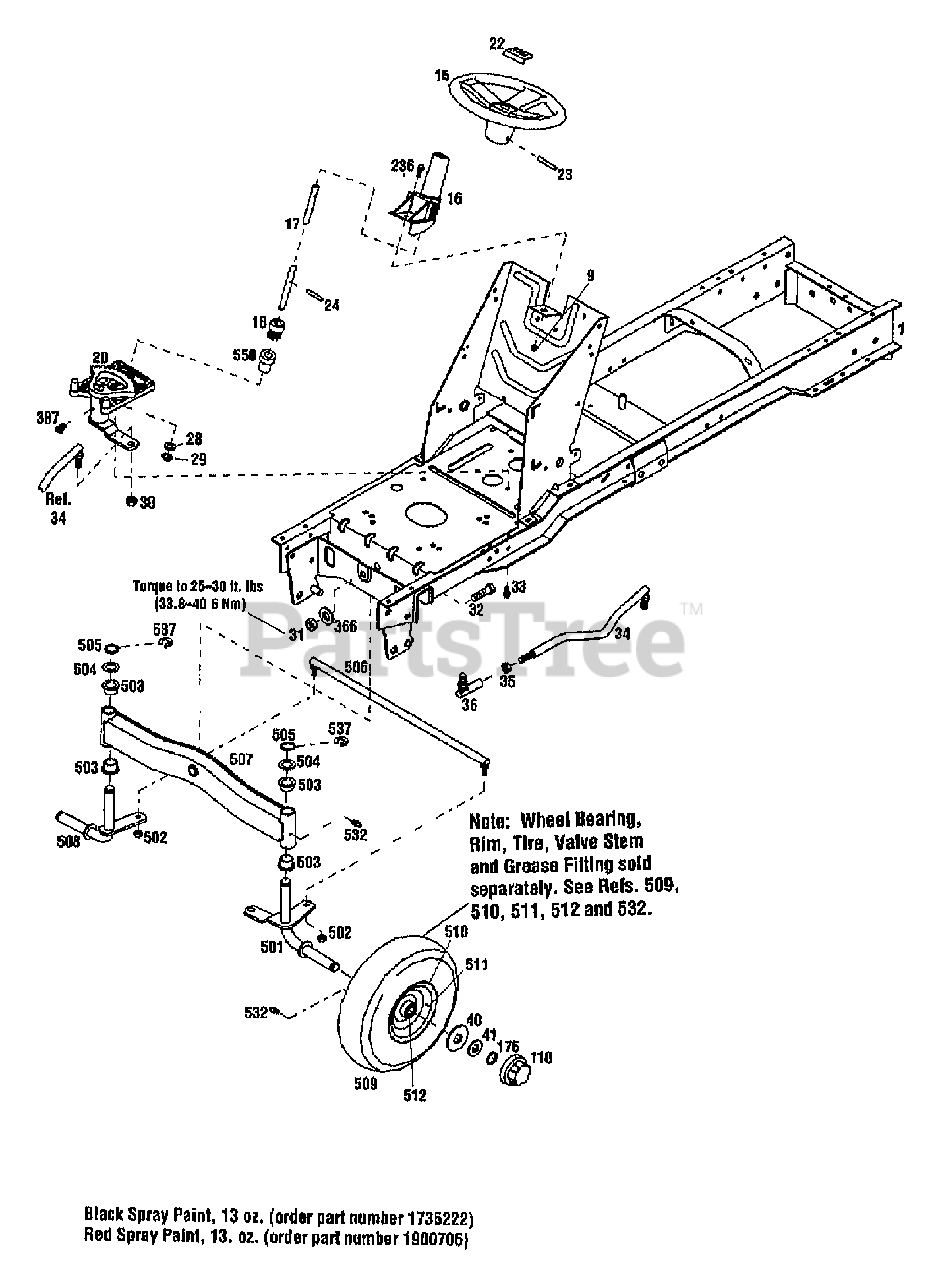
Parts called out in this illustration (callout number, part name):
9	NUT-HFLK 5/16-18 ZP
15	WHEEL-STEERING
16	SUPPORT-STEERING SHAFT
17	SHAFT-STEERING
18	GEAR-PINION
20	ASSM-STEERING GEAR
22	CAP-STEERING
23	PIN-ROLL .25X2.25
24	PIN-ROLL 1/4 X 1-1/4
28	WASHER-1.0X.64X.09
29	RING-RETAINING
31	NUT-H/LK 5/8-11
32	SCR-HH
33	SCR-HFLK 5/16-18X.75
34	LINK-DRAG
35	NUT-JAM
36	JOINT-BALL
40	WASHER-SPEC .75X2.50
41	WASHER-1.38 X.765X .06 ZP
110	CAP-HUB
236	SCR-HFLK 5/16-18X.75 ZP
366	WASHER-1.75X.687X.134 ZP
387	FITTING-GREASE 90 DEGREE
501	ASSM-SPINDLE LH
502	NUT-LOCK
504	WASHER-1.25X.765X.049
505	RING-HEAVY EXT HD 1.0 ID
506	KIT-TIE ROD W/HDW
508	ASSM-SPINDLE WHEEL RH
509	TIRE 15X6.00-6RS
510	DISC WHEEL
511	STEM-VALVE
512	BEARINGS-WHEEL
532	FITTING-GREASE 1/4-28X2.00
537	RING-RET."E".577 ID
550	BEARING
